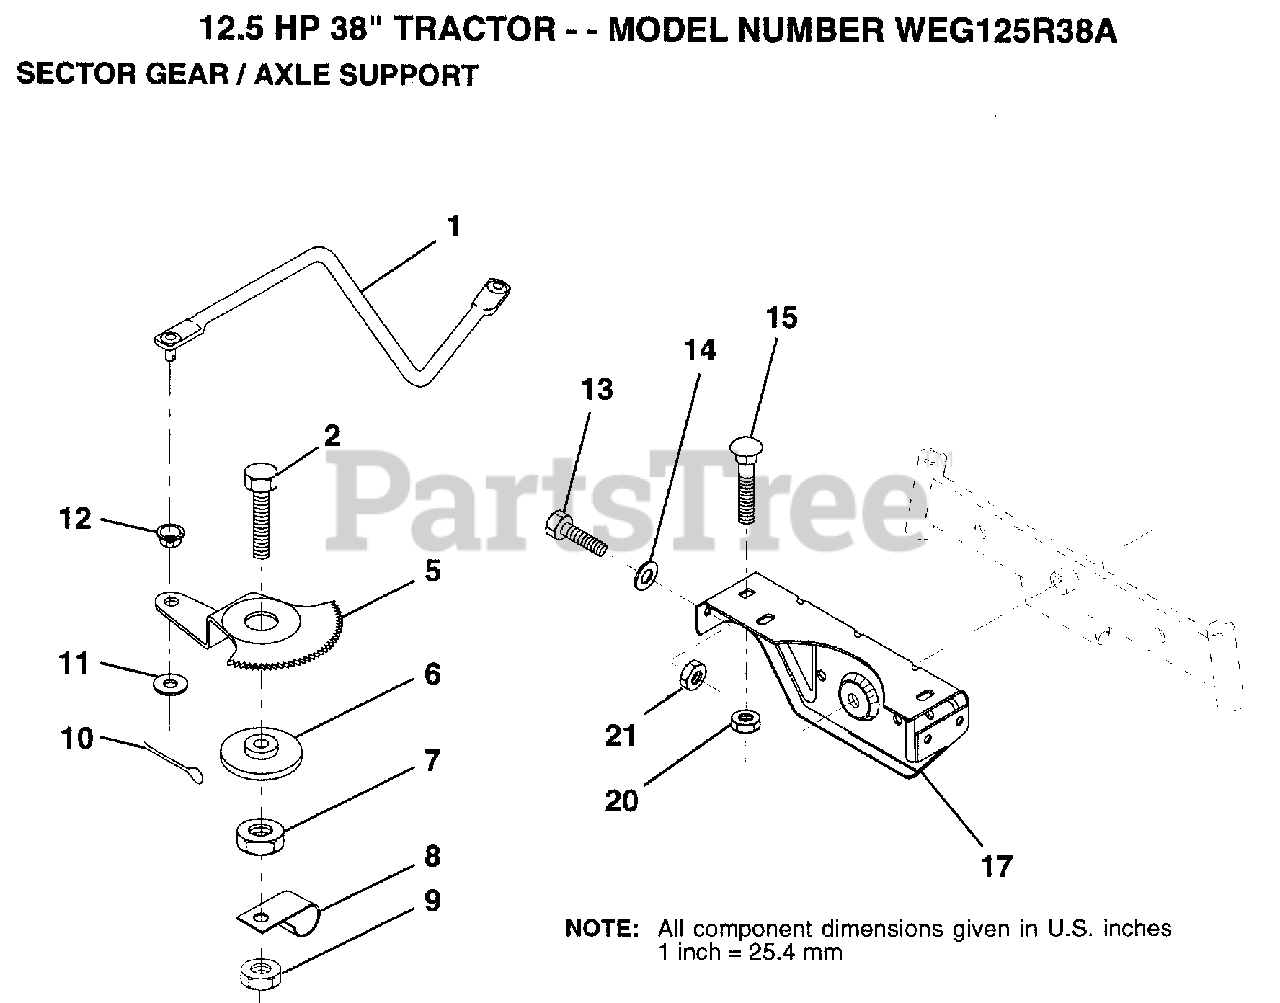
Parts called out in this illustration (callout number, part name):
1	DRAG LINK
2	"BOLT,HEX"
5	GEAR SECTOR
6	BUSHING
7	NUT
8	CLIP INSULATOR
9	NUT LTV
10	COTTER PIN
11	WASHER
12	BUSHING.DRAGLINK
13	BOLT
14	WASHER
15	BOLT
17	SUPT AXLE FRONT
20	NUT
21	NUT
